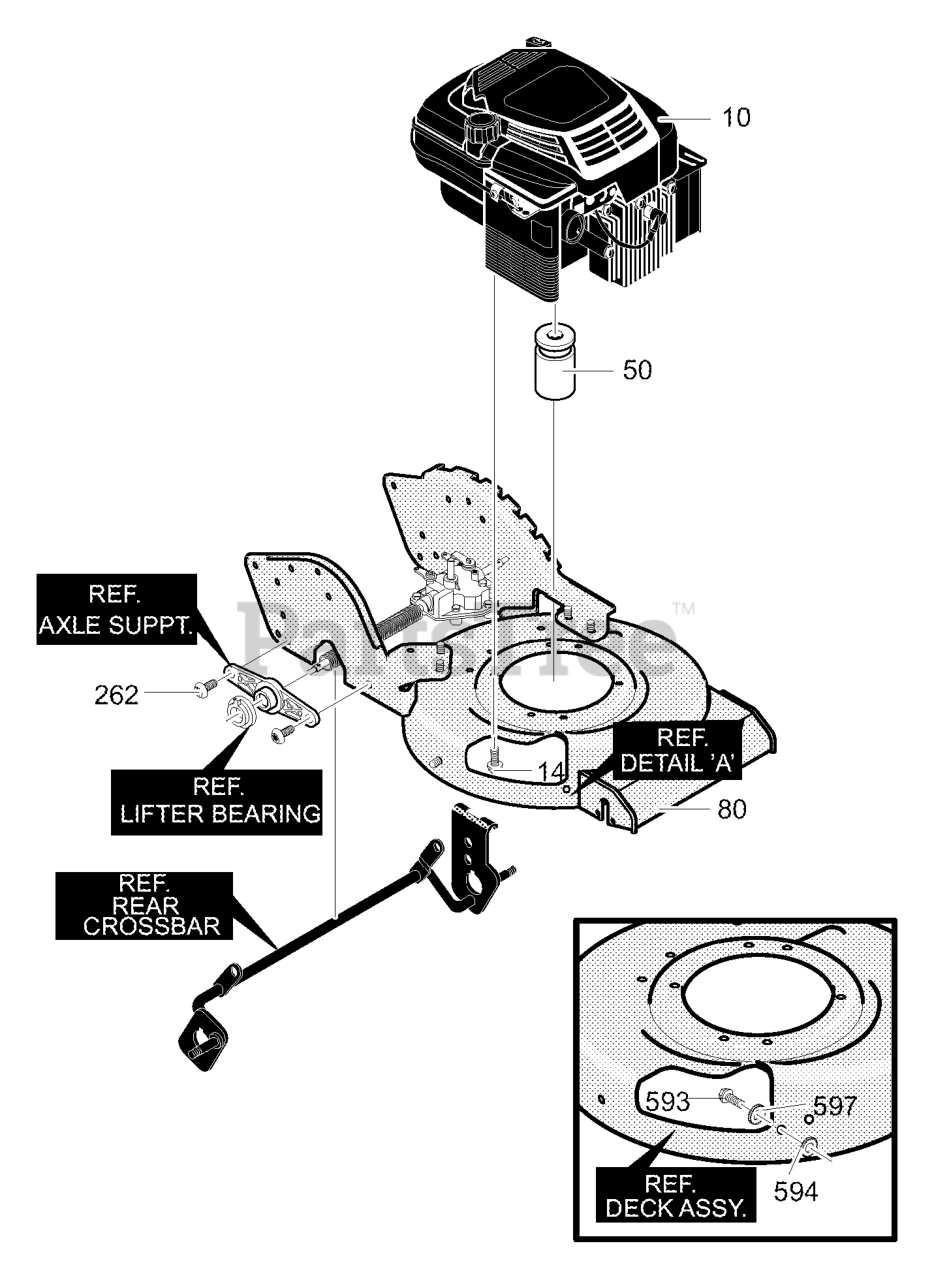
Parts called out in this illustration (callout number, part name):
14	Screw, 3/8-16 x 1.00
50	Adapter, Blade Pulley
80	Frame Assy.
262	Screw, 5/16-18 x 0.63
593	Bolt, 5/16-18x.63 Carr.
594	Nut, Retainer
597	Flatwasher
